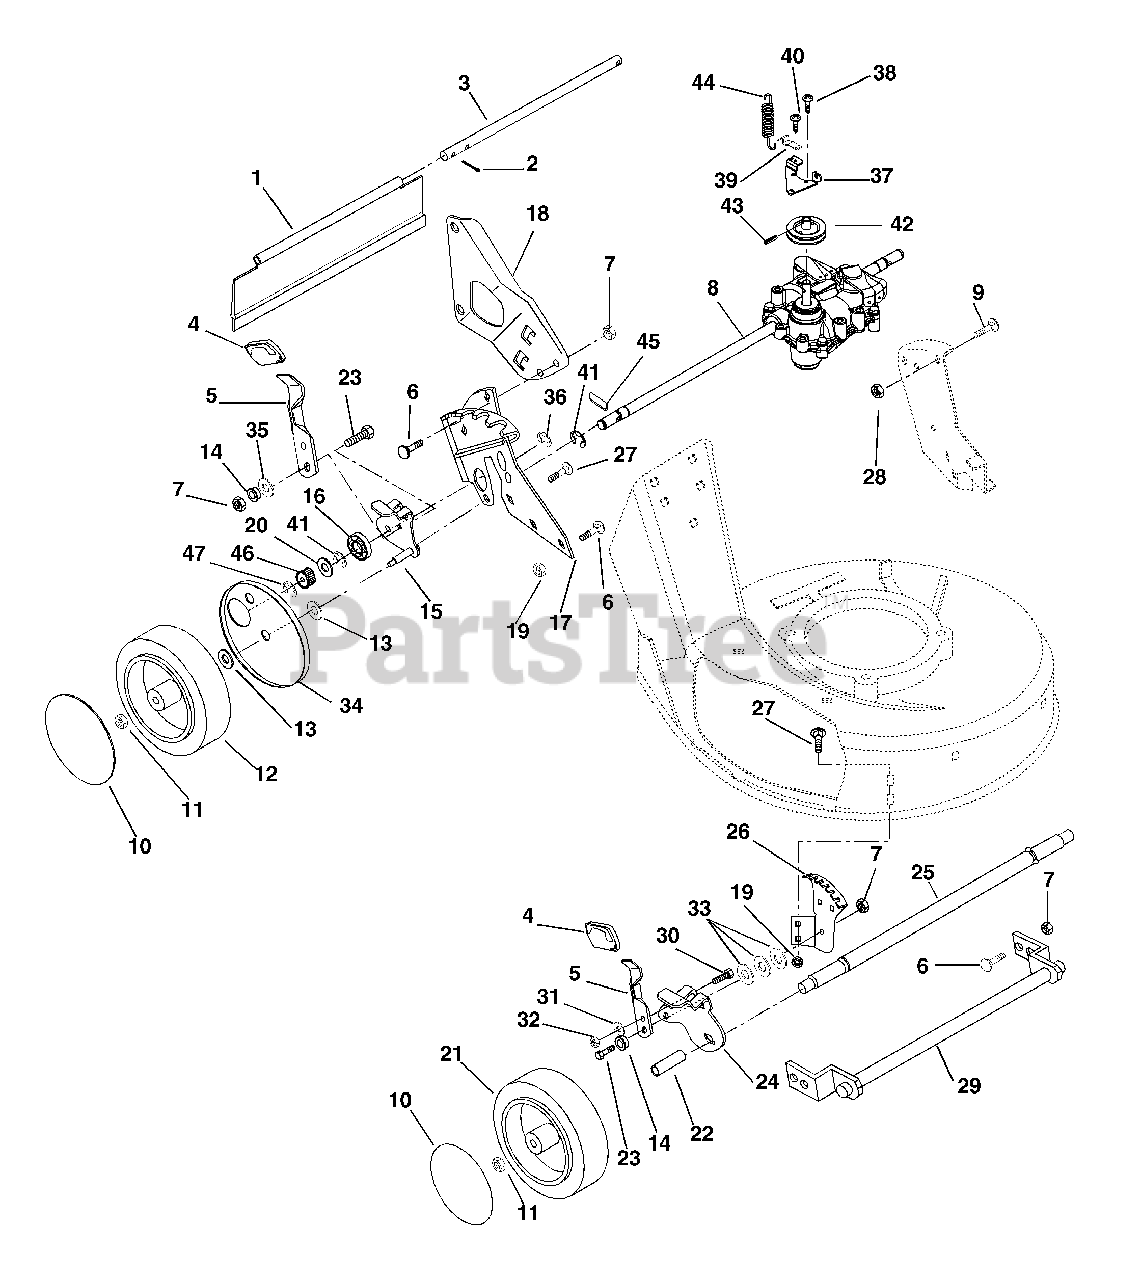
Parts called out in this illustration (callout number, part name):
1	GUARD-REAR PROTECTIVE
2	@PIN-CTR .06X.50 EXTPRSQCT YWZ
5	HEIGHT ADJUSTMENT LEVER
6	@BLT-RHDSSQNK .31-18X.62 G5YZ
7	@NUT-LK-CTR .31-18 YWZC
8	TRANSMISSION-TUFF TORQ TL3C
9	BLT-RDHDSQNK .31-18X1.0 SHTYZ
10	COVER-WHEEL
11	NUT-JAM-LK-NYL .438-14 YWZC
12	WHEEL-REAR W/GEAR TEETH
13	@WSHR-FL-STL.50X1.25X.083 YWZC
14	BSHG-FLG .32X.500X.344X.880
15	ADJUSTER-HEIGTH WELD ASSY,RH
15	ADJUSTER-HEIGTH WELD ASSY,LH
16	BRG-BALL .500X1.38X.437
17	QUADRANT-REAR LH WELD ASSY
17	QUADRANT-REAR, RH WELD ASSY
18	RH HANDLEBAR MOUNT WELDMENT
18	LH HANDLEBAR MOUNT WELDMENT
19	@NUT-SPNLK-FLG .312-18 YWZC
20	WSHR-FL-STL .505X1.00X.062YWZC
21	WHEEL-FRONT
22	SPACER .52X.75X.56
23	@BLT-HEX .31-18X1.00 GR5 YWZC
24	ADJUSTER-HEIGHT,FRONT LH
24	ADJUSTER-HEIGHT,FRONT RH
25	AXLE-FRONT
26	QUADRANT-FRONT LH
26	QUADRANT-FRONT RH
27	@BLT-RDHDSQNK .31-18X.50 G5YZ
28	@NUT-LK-NYL .312-18 YWZC
29	RETAINER-DETHATCHER WELD ASSY
30	@BLT-HEX .25-20X.50 GR5 YWZC
31	@WSHR-FL-STL.281X.62X.065 YWZC
32	@NUT-LK-CTR .25-20 YWZC
33	WSHR-FL-STL .347X1.254X.048YWZ
34	COVER-WHEEL INNER,LH
34	COVER-WHEEL INNER,RH
35	@WSHR-FL-STL.531X1.06X.095YWZC
36	RG-RTNG-EXT 1.625X.062
37	BRACKET-TRANSMISSION MOUNT
38	@SCR-TAP .25-20X.50 HWH TR YWZ
40	@SCR-TAP 8-32X.50 HWH TR YWZC
41	RG-RTNG-EXT .500X.035
42	SHEAVE-3.75X.395 W/HUB
43	PIN-ROLL .188X.88
44	SG-TENS .051X.50X5.30XWLD12
45	KEY-RATCHET
46	PINION/RATCHET-LH 15T
46	PINION/RATCHET-RH 15T
47	RG-RTNG-EXT .438X.025
